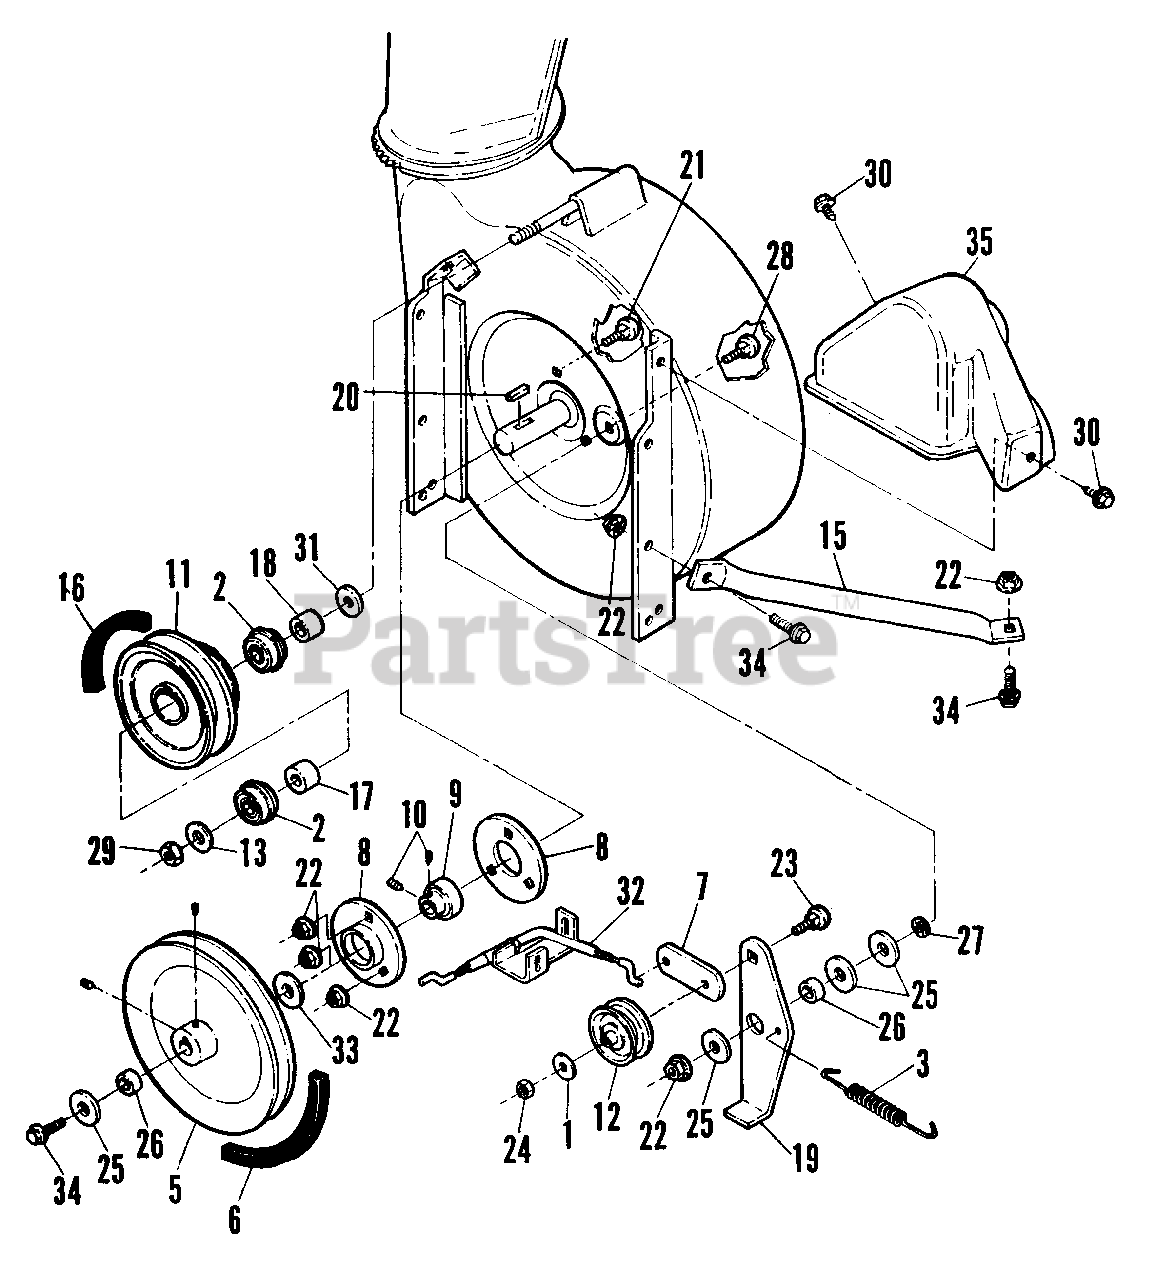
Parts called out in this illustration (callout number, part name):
1	WASHER, .406 x .812 x .080
2	BEARING
3	SPRING, 4"
5	SCREW, 5/16 Socket Head Set
6	V-BELT, 35.24
7	CABLE LINK
8	HOUSING, Bearing
9	BEARING
10	SCREW, #10 - 32 Socket Head Set
11	SHEAVE, Reduction
12	IDLER, 2.47" O.D.
13	WASHER, .635 x .985 x .05
15	BRACE, R.H.
16	V-BELT 68-1/2" (Engine Drive)
17	SPACER, .64 x .88 x .765
18	SPACER, .64 x .88 x 1.42
19	ARM, Idler Ass'y.
20	KEY, 3/16 Sg. x 3/4 Lg.
21	BOLT, 5/16 - 18 x 3/4" Short Neck Carriage
22	NUT, 5/16 - 18 Hex Flange Lock
23	BOLT, 3/8 - 16 x 1 1/2" Carriage (Flat Hd)
24	NUT, 3/8 - 16 Hex Lock
25	WASHER, 5/16" x 1-1/4" x 3/32" Flat
26	SPACER, .328 x .63 x .156
27	BOLT, Retainer
28	BOLT, Carriage Short Neck, 5/16 - 18 x 1
29	NUT, 5/8 - 18 Hex Lock
30	SCREW, 5/16 - 18 x 3/4" Hex Thread Forming
31	WASHER, .656 x 1.31 x .094
32	CONTROL CABLE
33	SPACER, .766 x x .25
34	SCREW, 5/16 - 18 x 5/8 Flange Lock
35	COVER, Belt
